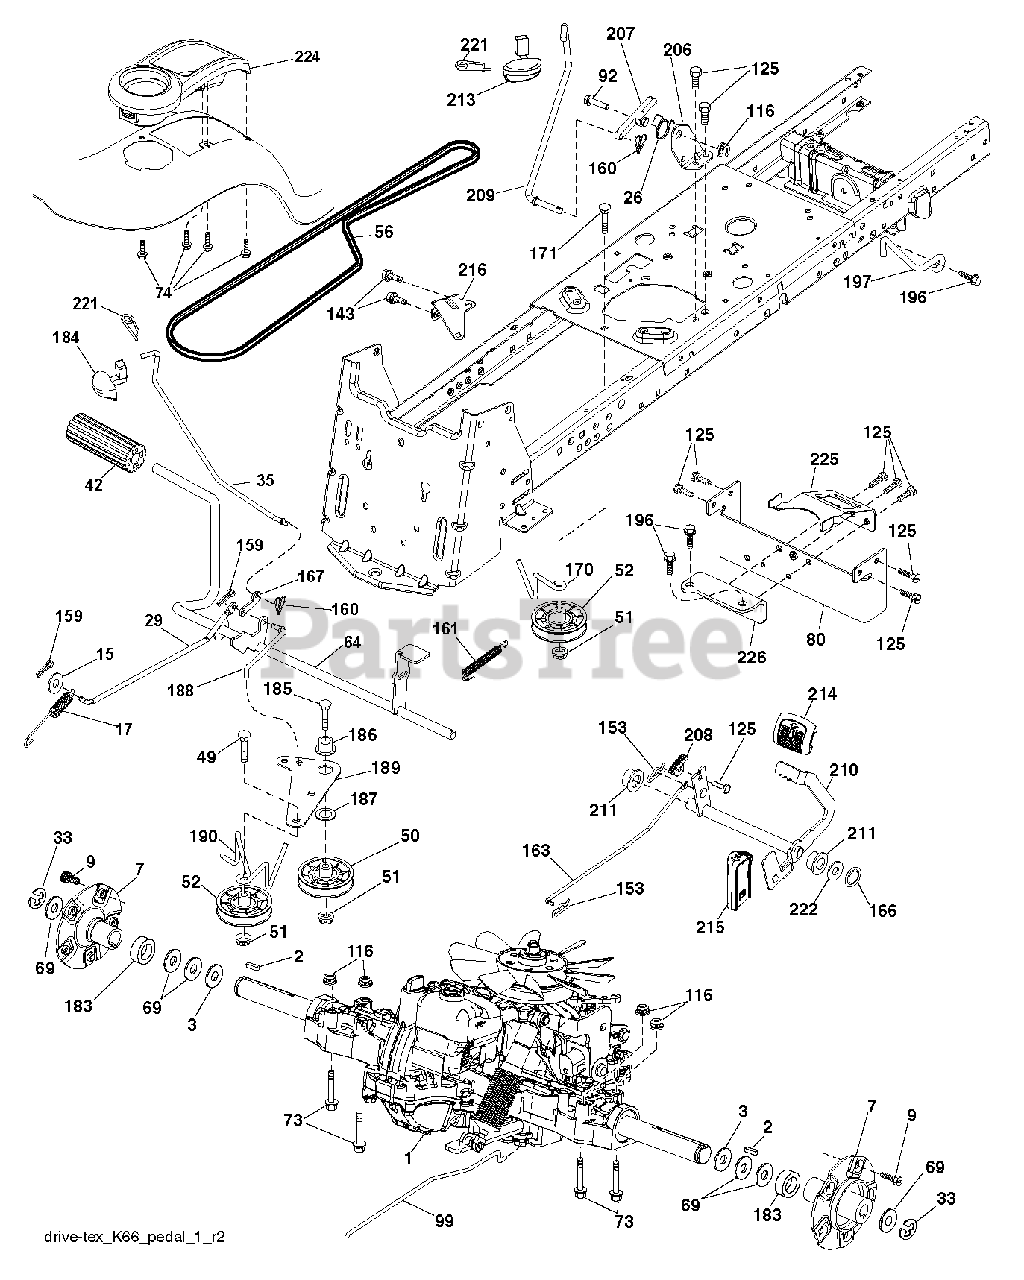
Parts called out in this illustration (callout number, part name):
7	HUB.ASM.WHEEL.REAR.23"TEX
17	SPRING.BRAKE.K46
26	SPRING.RETURN.CRUISE
29	ROD.BRAKE.K66
33	E RING HYT
35	ROD.BRAKE.PARTK.HUSQ.TEX
42	PEDAL COVER T
49	BOLT
50	IDLER.FLAT.910.OFFSET
51	NUT LOCK FLG 3/8-16 UNC
52	IDLER.V-GROOVE.910.OFFSET
64	SHAFT.ASM.PEDAL.BRK.CNTR
73	BOLT HEX 5/16-18 GR 5
74	SCREW.HI-LO.CONSOLE
80	STRAP.TORQUE.K66
92	BOLT
99	ROD.SPRING.BYPASS.K66.GT.Z
116	NUT LOCK HEX FLANGE 5/16-18
125	SCREW
153	RETAINER M
159	COTTER PIN
160	RETAINER CLIP
161	SPRING, RETURN LT
163	ROD.PEDAL.CONTROL
166	NUT.PUSH.625
167	LATCH.BRAKE.SPRING
170	KEEPER.V-IDLER.CENTER.
171	BOLT
183	SPACER.AXLE.HG.TEX
184	HANDLE.PARKG.BRK.HUSQ/PRED.667
186	SPACER.RETAINER
187	WASHER 12/32X2X10GA
188	LINK.CLUTCH.GROUND.DRIVE
189	BELLCRANK.GROUND.DRIVE.TEX.
190	KEEPER.BELLCRANK.DRIVE
196	SCREW 3/8-16X1
197	BRKT.ANIT-ROTATION.CLU
206	BRKT.MOUNT.LATCH.CRUIS
207	LATCH.CONTROL.CRUISE
208	GEAR.SECTOR.CONTROL.CR
209	ROD.CONTROL.CRUISE.GT.
210	ROCKER.ASM.PEDAL.CONTR
211	BEARING.NYLON
213	KNOB.CONTROL.CRUSIE.HU
214	PAD PEDAL FORWARD
215	PEDAL.REVERSE.TEX.GT.4
216	BRACKET.PULLEY.IDLER.W/TEX
221	RETAINER.SPRING.CLIP.H
222	WASHER 21/32 X 1-1/4 X 10 GA.
224	CONSOLE.TOOLBOX.PCH.ERGO.BLACK
225	KEEPER.BELT.TRANSAXLE.K66
226	BRACKET.MOUNT.TORQUE.K66.TG
